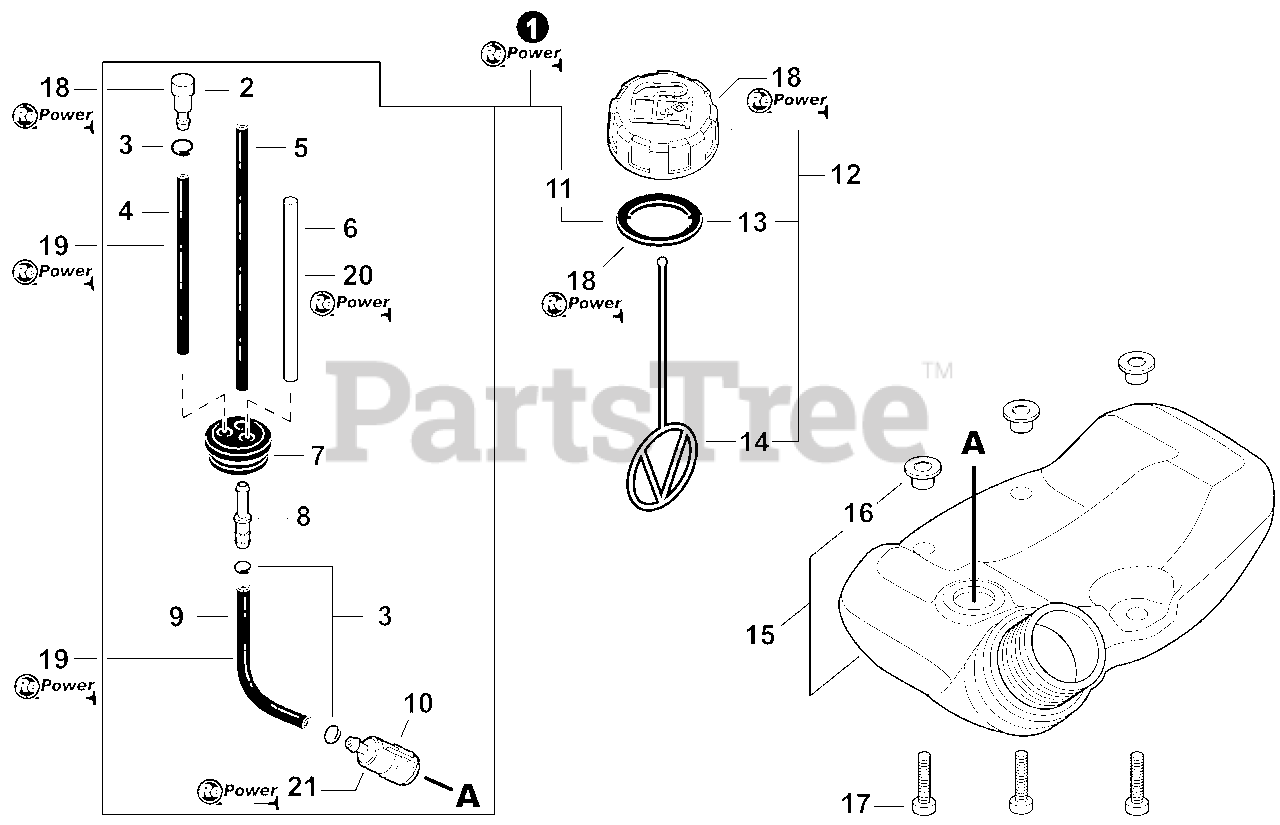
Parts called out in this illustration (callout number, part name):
1	FUEL SYSTEM KIT
2	VENT ASSY
4	PIPE, FUEL 3x5x90 BLACK
5	PIPE, FUEL 3x5x74 BLACK
6	PIPE, FUEL 3x6x80 YELLOW
7	GROMMET, FUEL 5
8	CONNECTOR, PIPE 5x3.5
9	PIPE, FUEL 3x5x130 BLACK
10	FILTER, FUEL
11	GASKET, FUEL CAP
12	CAP ASSY, FUEL
13	GASKET, FUEL CAP
14	CONNECTOR, CAP L= 123
15	TANK ASSY, FUEL
16	COLLAR 5
17	BOLT, TORX 5x20
18	CAP/VENT KIT - REPOWER
19	BULK PIPE - 3x5 MM BLACK (4 PIECESx2 M)
20	BULK PIPE - 3x6 MM CLEAR (4 PIECESx2 M)
21	TUNE-UP KIT - REPOWER
